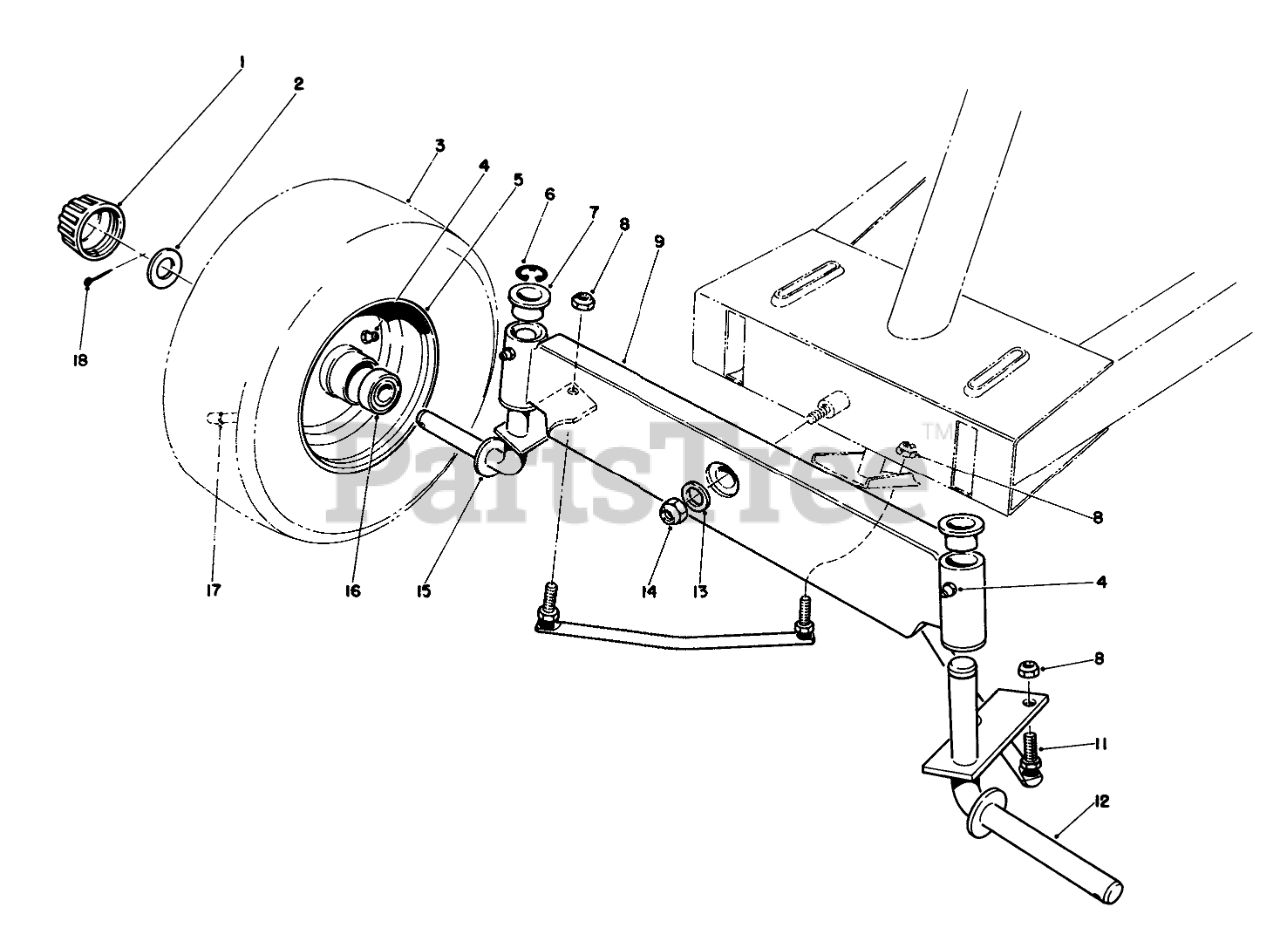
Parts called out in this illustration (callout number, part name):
1	CAP-HUB
2	WASHER-PLAIN
3	TIRE,PNEU.11X4.00X5
4	FITTING-GREASE
6	E-RING
7	BEARING-FLANGE
8	NUT-LOCK
9	Axle-Front
11	TIE ROD ASM
12	Spindle-L.H.
13	WASHER-FLAT
14	NUT-LOCK, NI
15	Spindle-R.H.
16	Bearing
17	STEM-VALVE
18	PIN-COTTER
